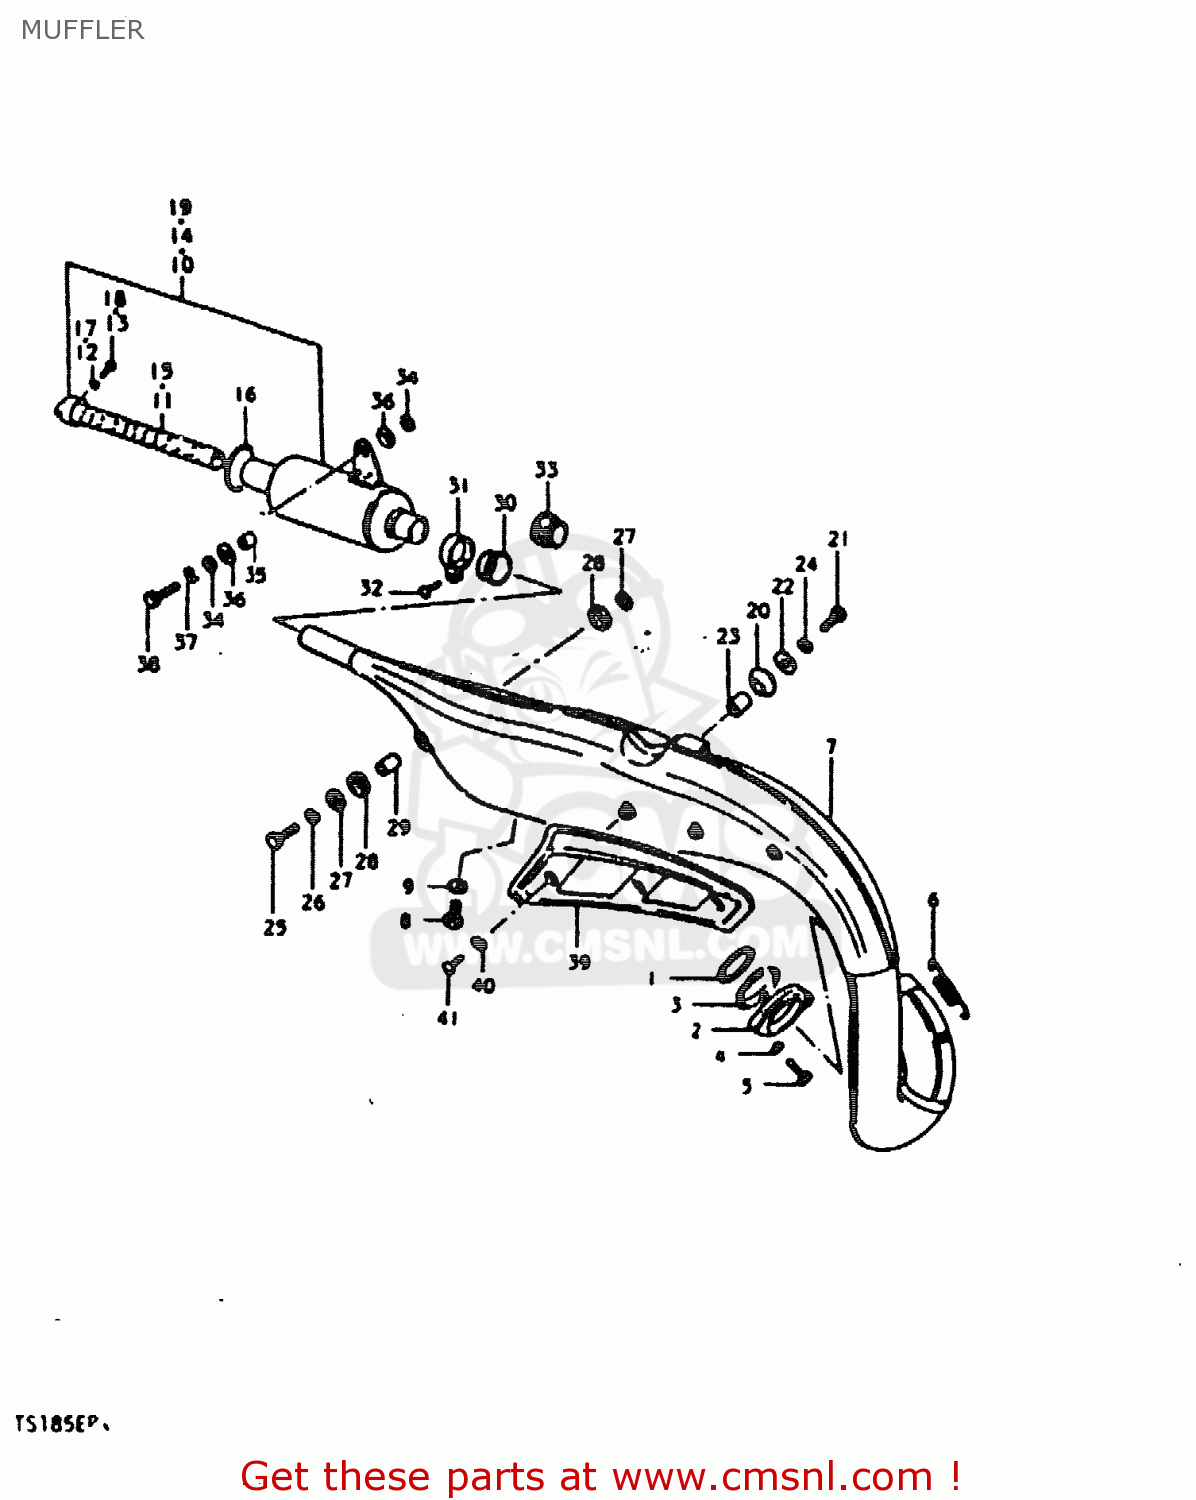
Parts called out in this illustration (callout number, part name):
1	GASKET,EXHAUST PIPE (NAS)
2	CLAMP,EXHAUST PIPE
3	CUSHION,EXHAUST PIPE
4	LOCK WASHER
5	BOLT
6	SPRING
7	BODY,MUFFLER
8	BOLT 10X9
9	GASKET(10X14X3.6) (NAS)
10	MUFFLER ASSY,2ND
11	PIPE,BAFFLE
12	LOCK WASHER
13	SCREW
20	DAMPER,MUFFLER,FR
21	BOLT
22	WASHER
23	SPACER (8X12X15)
24	LOCK WASHER
25	BOLT
26	LOCK WASHER
27	WASHER (8.2X20X1.6)
28	CUSHION
29	SPACER (8.6X13.8X9.8)
30	CONNECTOR,MUFFLER
31	CLAMP
32	SCREW
33	CONNECTOR,MUFFLER
34	WASHER
35	SPACER
36	CUSHION
37	LOCK WASHER
38	BOLT
39	COVER,MUFFLER
40	LOCK WASHER
41	SCREW
